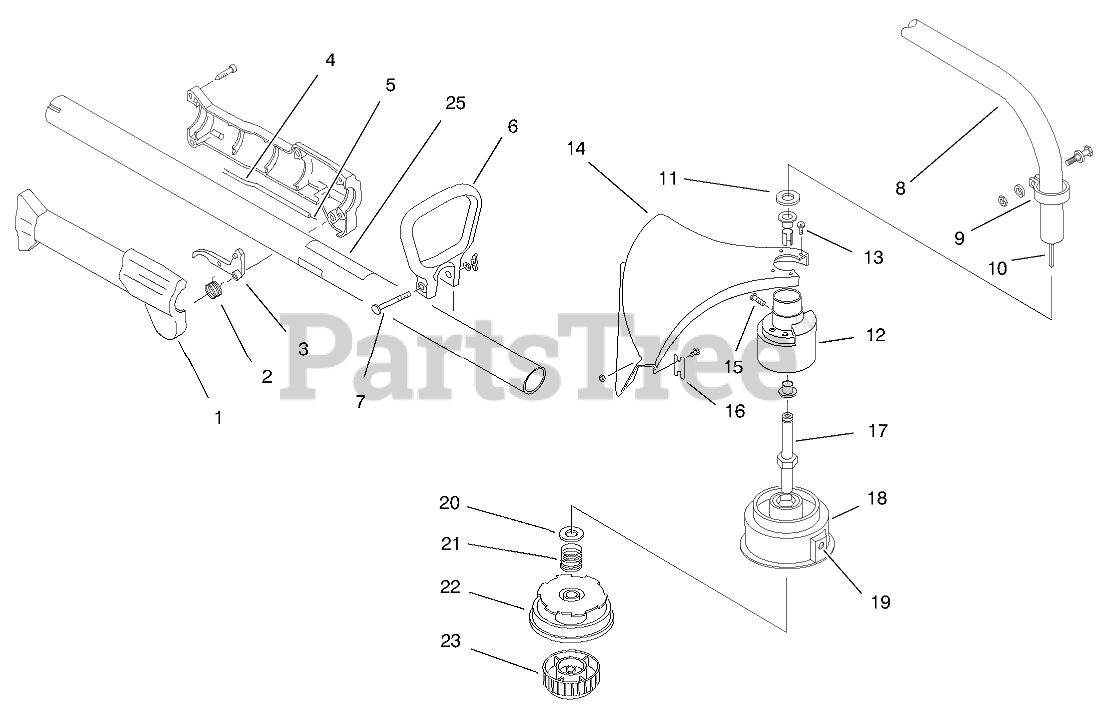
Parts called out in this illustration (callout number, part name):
1	Throttle Housing & Trigger Asm.
2	SPRING - TRIGGER
3	HSG - THROTTLE TRIGGER
4	Throttle Cable Housing
5	Throttle Cable
6	D-Handle
7	HARDWARE - D-HANDLE
8	DRIVE SHAFT HSG ASM
9	CLAMP ASM - UPPER
10	SHAFT - FLEX, 48.94
12	BUSHING HSG ASM
13	Guard Mounting Screw
14	Guard and Blade Asm. (Incl. Ref. #16)
15	Anti-Rotation Screw
16	BLADE ASM
17	Shaft-Spool
18	OUTER SPOOL EYELET ASM
19	EYELET
20	RETAINER ( 10 PACK)
21	SPRING
22	REEL - INNER
23	SMALL BUMP KNOB ASM
25	DECAL - SAFETY SYMBOLS
